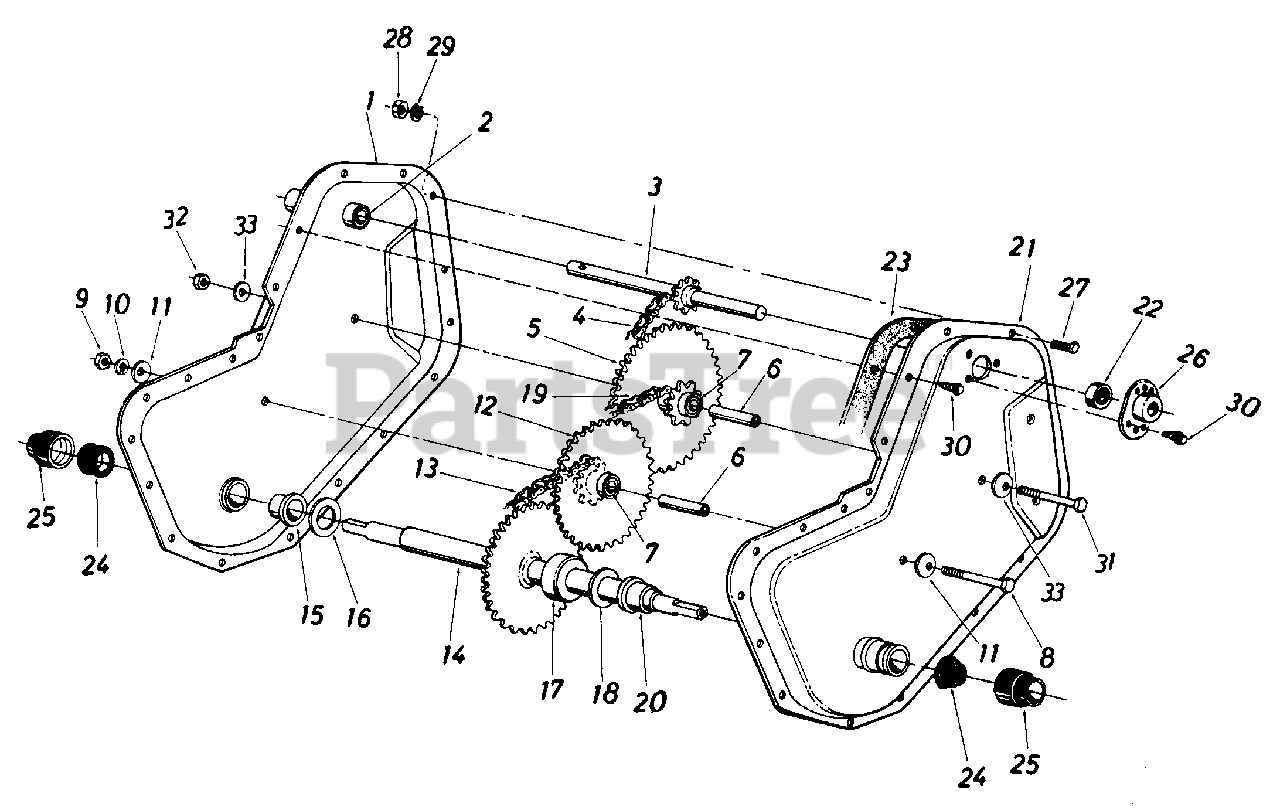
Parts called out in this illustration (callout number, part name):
1	Chain Case Half Ass'y. R.H.
2	Bearing 5/8" I.D. x .813" O.D. x 1.31" Lg.
3	Input Shaft Ass'y.
4	Chain #35 3/8" Pitch x 44 Link
5	Sprocket and Hub Ass'y.
6	Bearing Inner Axle
7	Sleeve Brg. 5/8" I.D. x 3/4" O.D. x 1.50
8	Hex Bolt 3/8-24 x 2.50" Lg.
9	Hex Ins. L-Nut 3/8-24 Thd.
10	L-Wash. 3/8" I.D.
11	Bell-Wash. .41" I.D. x 1.13 O.D. x .03
12	Sprocket & Hub Ass'y. 9T-22T
13	#420 Chain 1/2 Pitch x 28 Links Endless
14	Wheel Shaft Ass'y.
15	Flange Bearing
16	Fl-Wash. .88" I.D. x 1.5" O.D. x .03
17	Spacer 7/8" I.D. x 13/4" O.D. x.68" Lg.
18	Fl-Wash. .88" I.D. x 1.50" O.D. x .03
19	#420 Chain 1/2" Pitch x 30 Links Endless
20	Flange Bearing
23	Gasket
25	Dust Cup
26	Bearing Housing
27	Hex Bolt 1/4-28 x 5/8" Lg.
28	Hex Nut 1/4-28 Thd.
29	L-Wash. 1/4" I.D.
30	Hex Wash. S-Tap Scr. 1/4-20x.50" Lg.
31	Hex Bolt 5/16-18 x 2.5" Lg.
32	Hex Cent. L-Nut 5/16-18 Thd.
33	Fl-Wash. 5/16" I.D.
